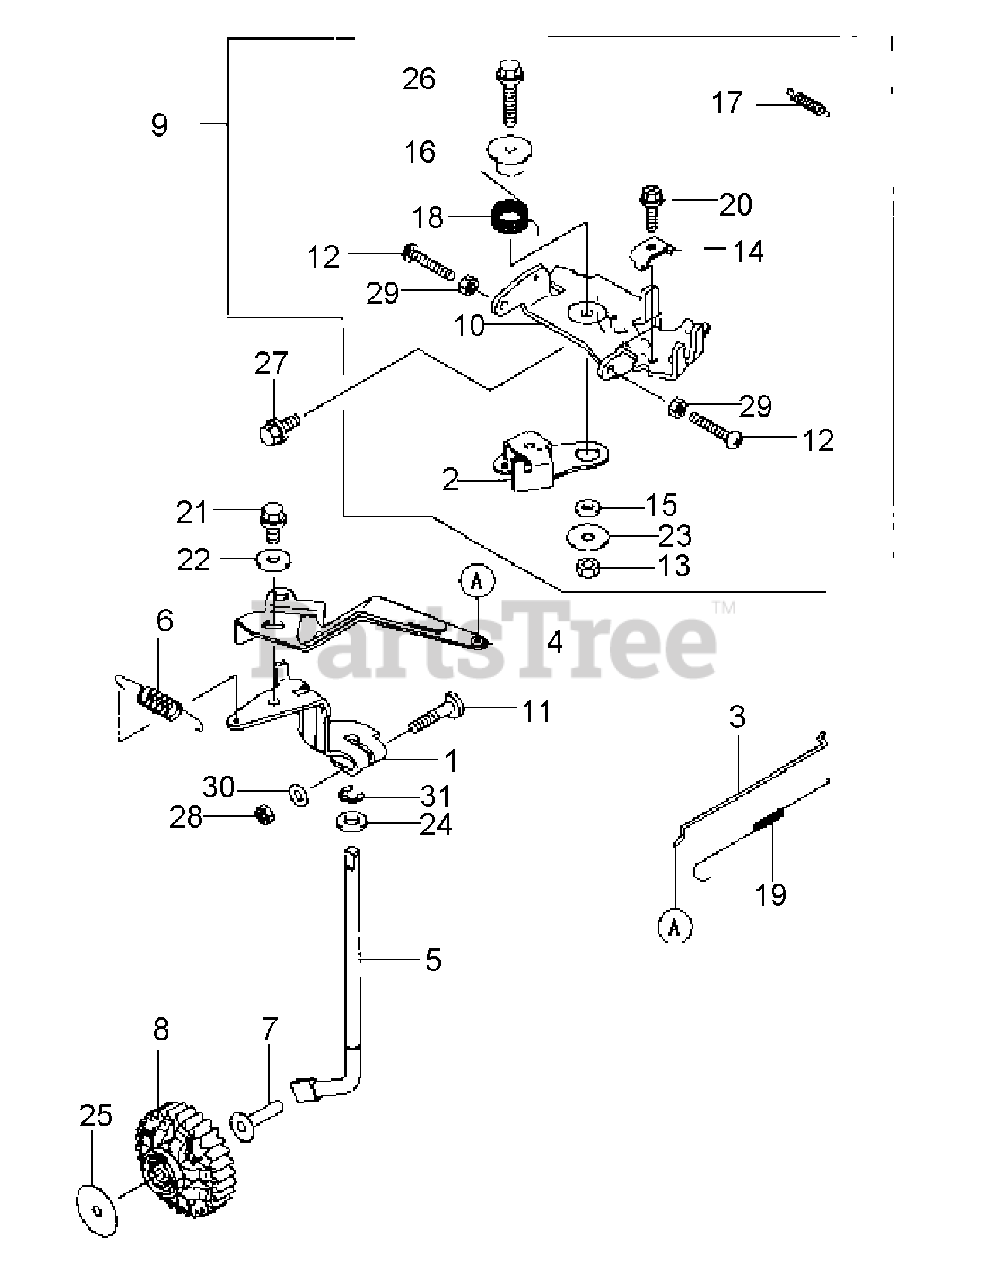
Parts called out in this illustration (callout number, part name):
2	THROTTLE LEVER
6	GOVERNOR SPRING
8	GOVERNOR ASSY.
9	CONTROL PANEL ASSY.
10	CONTROL PANEL
26	FLANGED BOLT
27	FLANGED BOLT
30	PLAIN WASHER
31	CIRCLIP- TYPE-E
